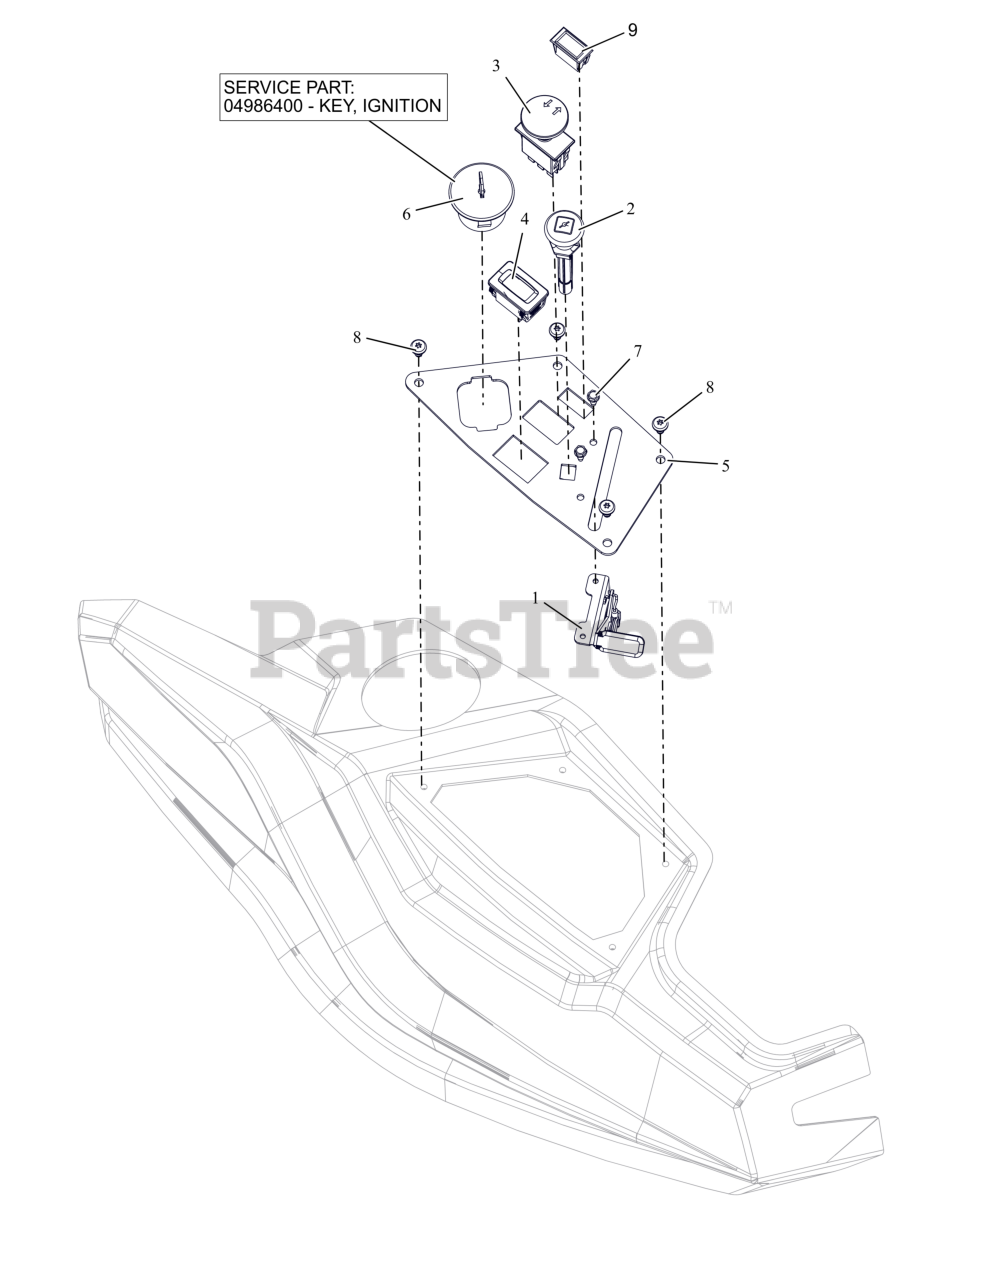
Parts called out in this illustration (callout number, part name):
1	CABLE, THROTTLE
2	CABLE, CHOKE (SNAP IN)
3	SWITCH, CLUTCH (YELLOW)
4	HOUR METER
5	PANEL- CONTROL
6	KEYSWITCH-IGNITION 3 POS
6	KEY, IGNITION
7	SCR,TAP #10-24X.50 HWH TR ZCC
8	SCR-PAN .25-15X.50 6L H/LZB500
9	SWITCH,BLANK
